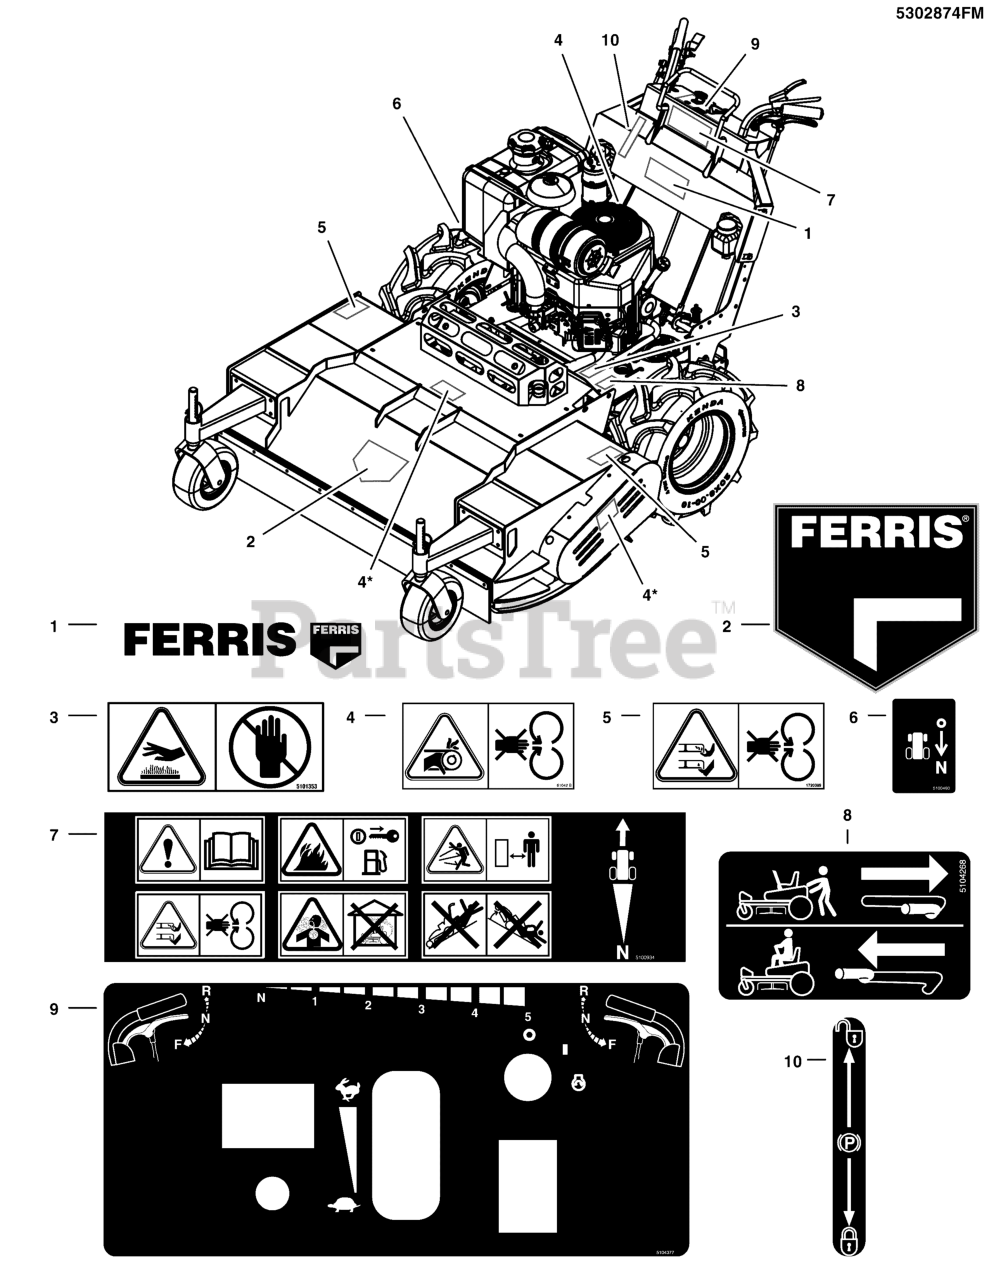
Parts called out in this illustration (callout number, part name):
1	DECAL, FERRIS TEXT & LOGO
2	DECAL, BRAND
3	DECAL, HAND IN FLAME
4	* DECAL, CE DANGER
5	DECAL-DANGER ROTATING BLADE SYMBOLS
6	DECAL, PEDAL
7	DECAL, CCW, CE
8	DECAL, TRANSAXLE RELEASE, WB
9	DECAL, DASH PANEL, WKB, MAN/ELEC START
10	DECAL, PARKING BRAKE SYMBOLS
